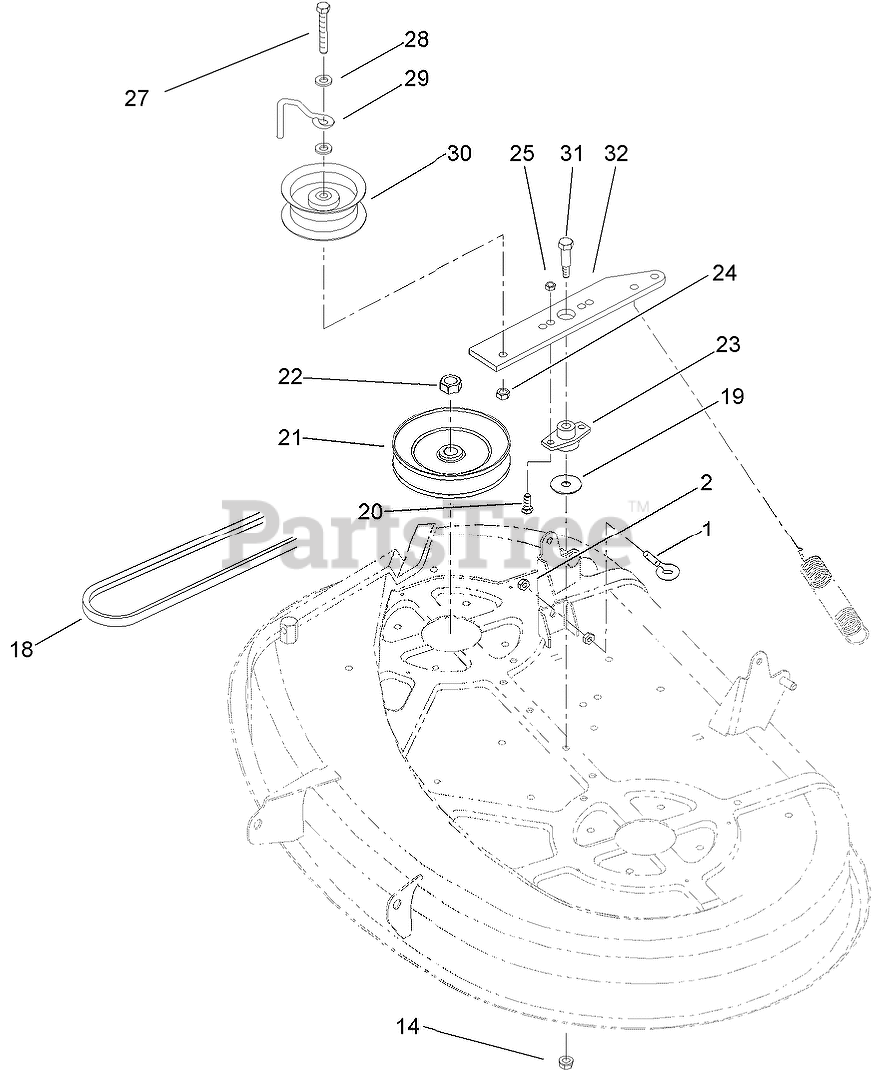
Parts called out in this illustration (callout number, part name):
1	EYEBOLT
2	NUT-JAM
14	NUT-LOCK, NI
18	BELT-V
19	WASHER-FLAT
20	SCREW-HH
21	PULLEY
22	NUT-HEX
23	BUSHING-ARM, IDLER
24	NUT-LOCK, NI
25	NUT-LOCK, NI
27	SCREW-HH
28	WASHER-FLAT
29	GUIDE-IDLER, BELT
30	PULLEY-IDLER, FLAT
31	SCREW-SHOULDER, HH
32	ARM-IDLER
